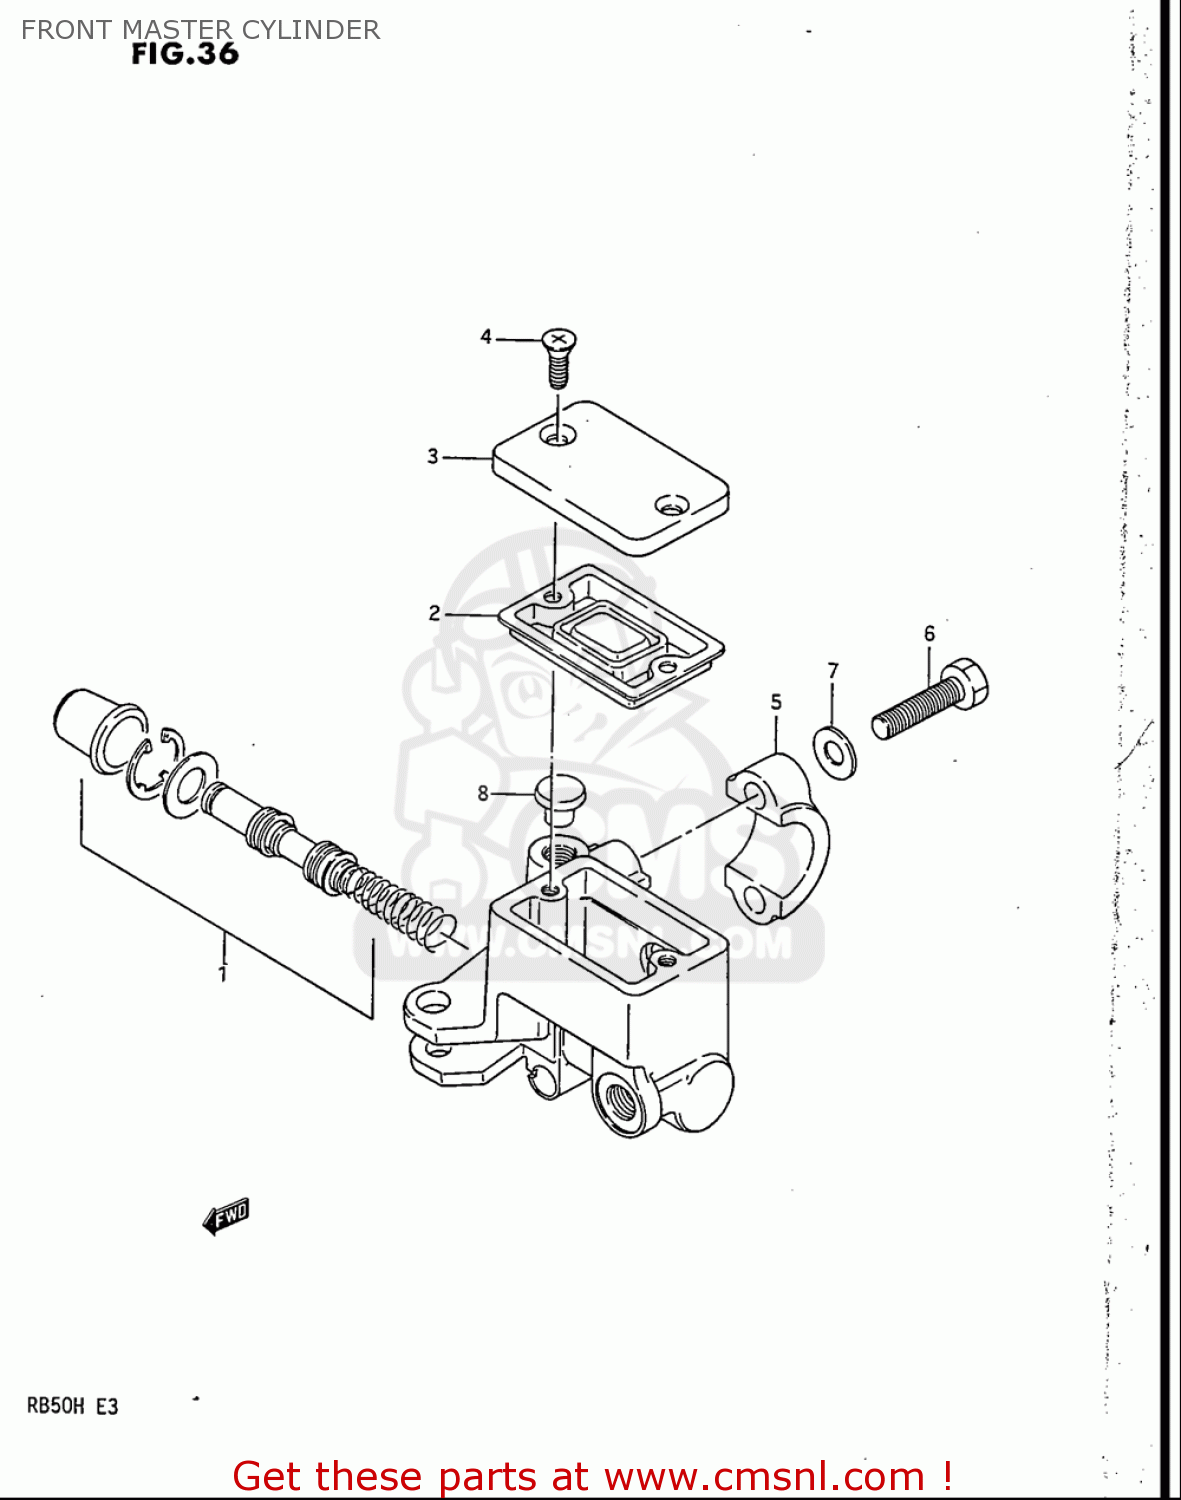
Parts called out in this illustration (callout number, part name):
1	PISTON & CUP SET
2	DIAPHRAGM
3	CAP
4	SCREW
5	HOLDER
6	BOLT
7	WASHER
8	PLUG(OD:12)
